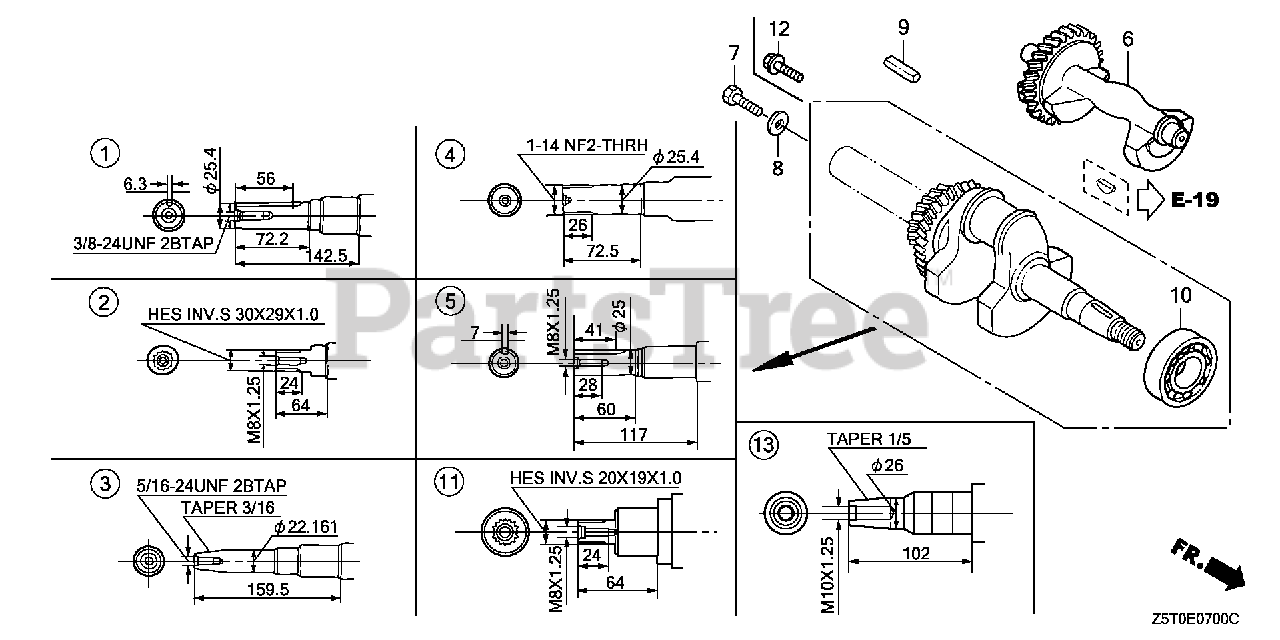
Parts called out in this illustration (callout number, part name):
4	CRANKSHAFT
6	WEIGHT, BALANCER
10	BEARING, RADIAL BALL (6207SH)
